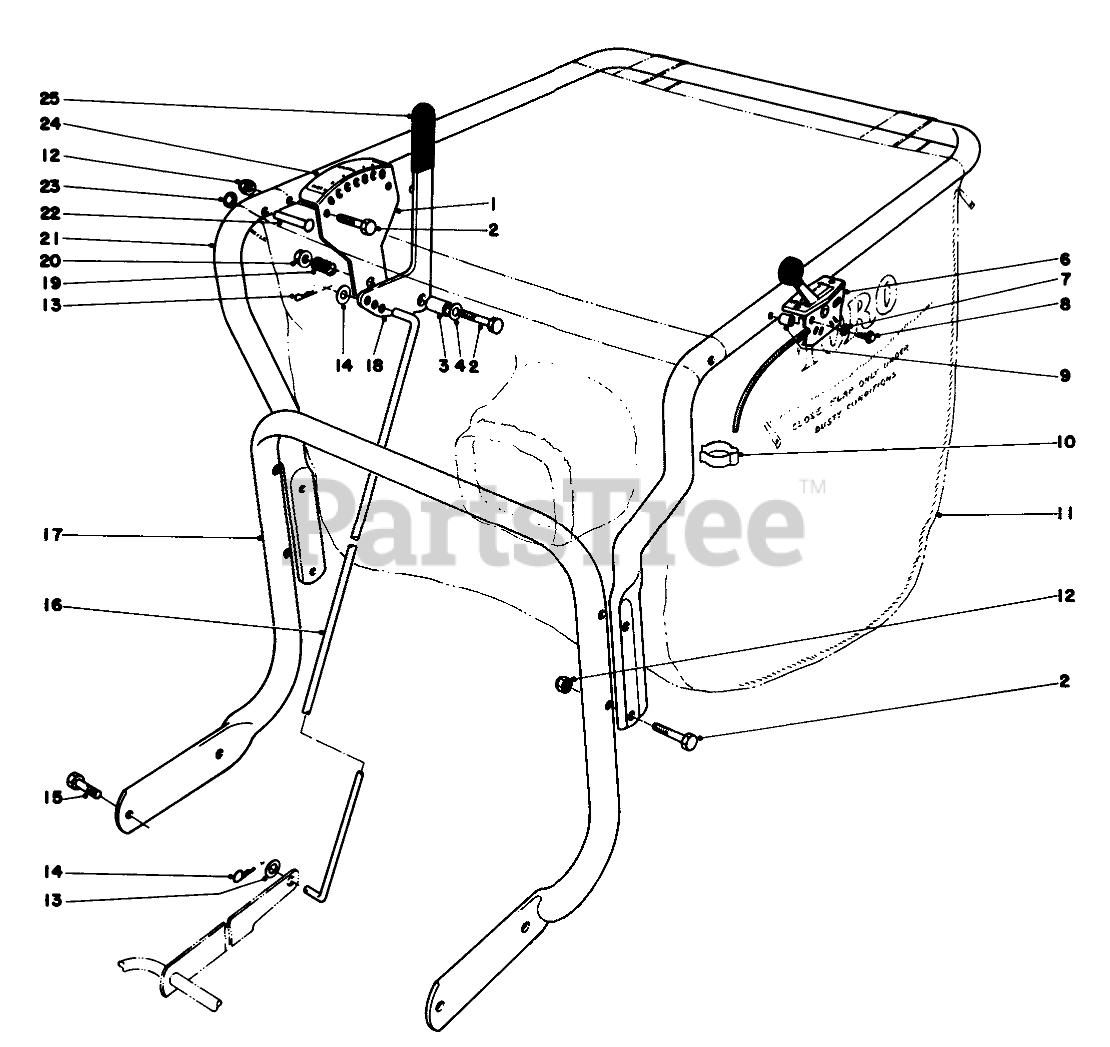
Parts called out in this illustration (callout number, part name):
1	Adjustment Bracket
2	SCREW-HH
3	SPACER
4	WASHER-FLAT
6	THROTTLE CONTROL
7	WASHER-LOCK, EXT
8	10-24 X 1 PAN HD SCR
9	SPACER
10	BODEN CLIP
11	Bag-Vacuum
12	NUT-LOCK, CONE
13	WASHER-FLAT
14	PIN-COTTER
15	SCREW-HH
16	HEIGHT ADJ. ROD
17	HANDLE
18	Handle-Adjustment
19	SPRING-COMPRESSION
20	NUT-HF
21	HANDLE-UPPER, VACUUM
22	RIVET
23	NUT-PUSH IN
24	HT ADJ DECAL
25	GRIP-HANDLE
